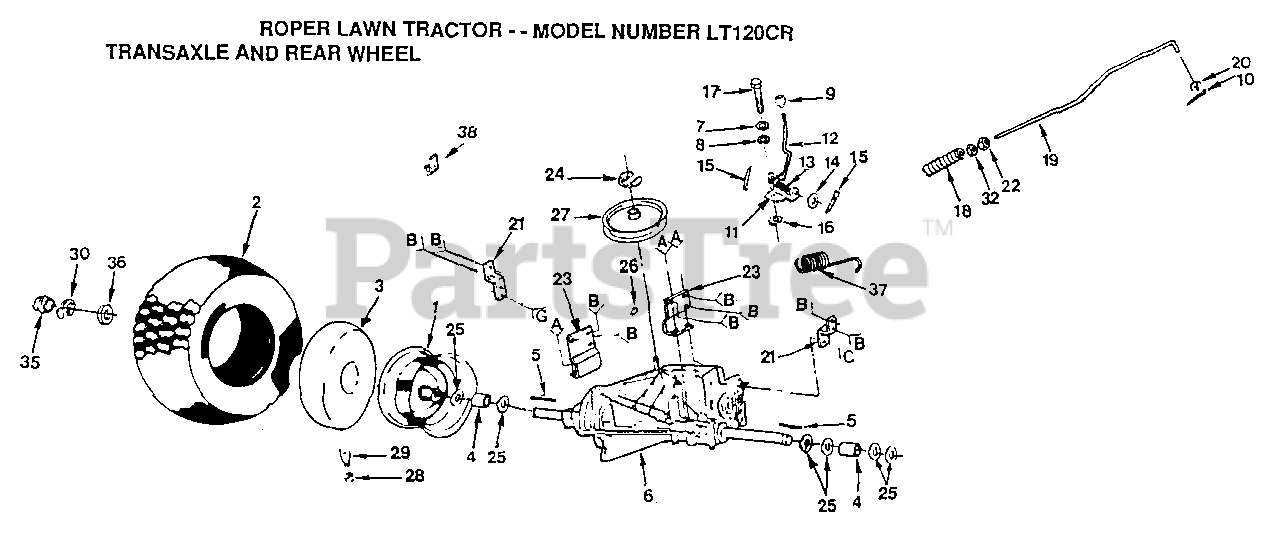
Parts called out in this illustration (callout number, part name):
3	TUBE.18X9.5-8
4	SPACER LT
6	TRANSAXLE FOOTE
7	LOCKWASHER
8	WASHER LT
9	KNOB.DUCKHEAD.1/2
10	COTTER PIN
11	PLATE SHIFT LT
12	ROD SHIFT
13	SPRING LT
14	WASHER
15	PIN COTTER 1/8
16	"LINK, CLUTCH T"
18	SPRING ROD LT
19	BRAKE ROD LT
20	WASHER
21	STRAP TORQUE
22	NUT
23	BRACKET LT
25	WASHER
28	VALVE CAP
29	VALVE STEM LT
30	E-RING LT
35	HUB CAP
36	WASHER
38	CLIP T
